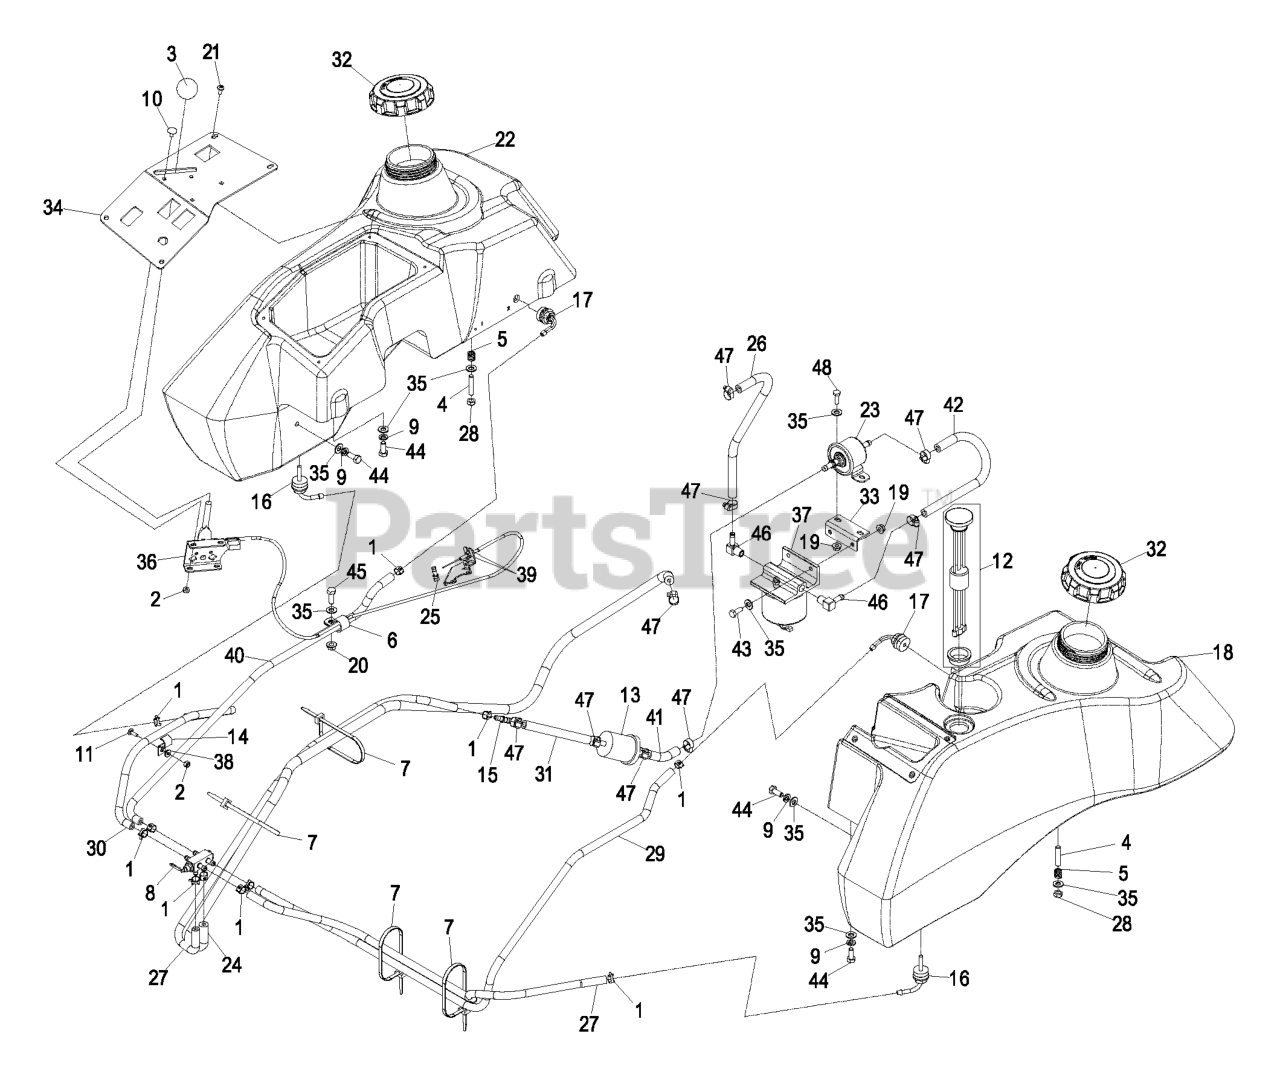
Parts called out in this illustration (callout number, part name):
2	NUT-LOCK, NI
3	KNOB-BALL
4	STUD
5	SPRING-TANK, FUEL
6	CLIP-LOOM
7	TIE-PLASTIC
8	VALVE-FUEL, DUAL FLOW
9	WASHER-LOCK
10	BOLT-CARR
11	BOLT-CARR
12	KIT, CT FUEL GAGE REPL.
13	P/N 12581-43012 Fuel, Filter
14	CLIP-HALF, LOOM
15	CONNECTOR
16	FITTING-FUEL, BULKHEAD
17	FITTING-FUEL, BULKHEAD
21	SCREW-PPH
22	ASM,DIESEL FUEL TANK RH
23	P/N 1g639-5203-0 Pump, Fuel
24	HOSE-FUEL
25	SWIVEL-STOP, CABLE
26	HOSE-FUEL
27	HOSE-FUEL
28	NUT-LOCK, NI
29	HOSE-FUEL
30	HOSE-FUEL
31	HOSE-FUEL
32	CAP-FUEL, DIESEL
33	BRACKET,FUEL PUMP
34	ASM,CONTROL PANEL W/ DECA
35	WASHER-PLAIN
36	CABLE,THROTTLE
37	FILTER HEAD ASM
38	WASHER-FLAT
39	NUT-JAM
40	HOSE-FUEL
41	HOSE-FUEL
42	HOSE-FUEL
43	SCREW-HH
44	SCREW-HH
45	SCREW-HH
46	FITTING-HYD, 90 DEG
47	CLAMP-WORM
48	SCREW-HH
